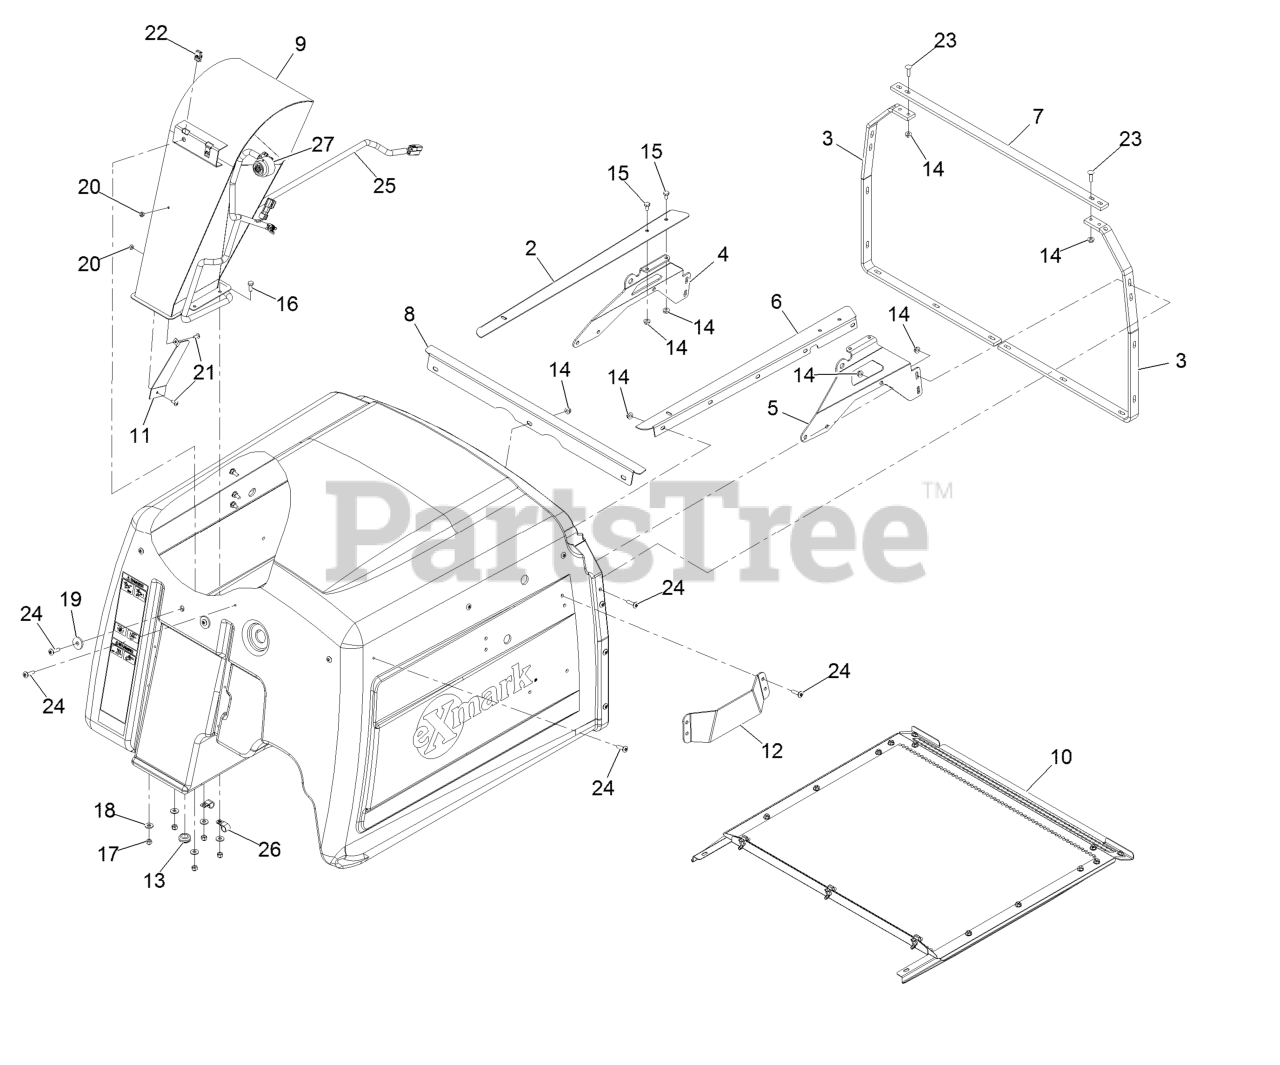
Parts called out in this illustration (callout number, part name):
2	Angle-Screen Track, RH
3	Reinforcement-Hopper
4	Brace-Door Pivot, RH
5	Brace-Door Pivot, LH
6	Angle-Screen Track, LH
7	Bracket-Frame Connect
8	Channel-Screen, Front
10	Hopper Screen ASM
11	Deflector-Discharge Chute
12	Plate-Guard
13	Grommet
14	Nut-Whizlock 1/4-20
15	Screw-HH 1/4-20 X 1/2
16	Screw-HH 1/4-20 X 3/4
17	Nut-Nyloc 1/4-20
18	Washer-1/4 Std
20	Nut-Nyloc #10-24
21	Screw-Truss HD #10-24 X 1/2
22	Nut-Retainer-Panel 1/4-20
23	Bolt-Carriage 1/4-20 X 1
24	Screw-Truss HD 1/4-20 X 1
25	Harness-Wire, Hopper
26	Clip-Loom 1/2
27	Alarm-Tone, Dual
